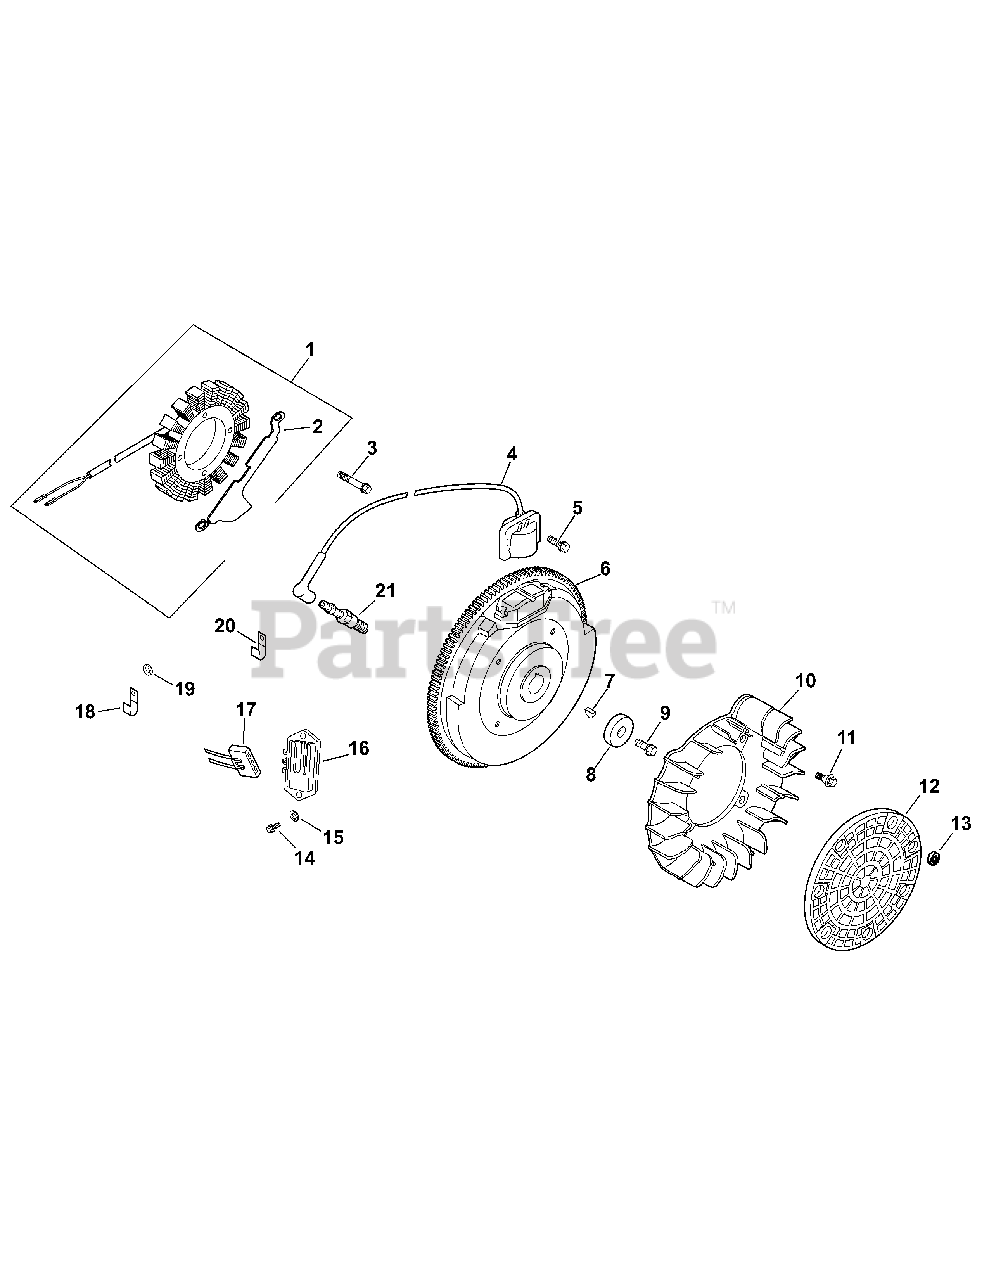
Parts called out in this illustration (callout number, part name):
1	Kit, 15 amp stator (Includes 2)
2	Bracket, stator wire
3	Screw, hex. cap M5x0.8x25 (2)
4	Module, ignition (2)
5	Screw, hex. flange M5x0.8x20 (4)
6	Flywheel
8	Washer, plain 3/8"
9	Screw, hex. flange M10x1.5x46
10	Fan
11	Bolt, shoulder (4)
12	Screen, grass
13	Retainer, grass screen (3)
14	Screw, phillips hd. 11-16x7/8" (2)
15	Washer, plain 3/16" (2)
16	Rectifier-regulator 15 amp
17	Connector (3 contact)
18	Clip, cable
19	Washer, plain 1/4"
21	Spark Plug (2)
